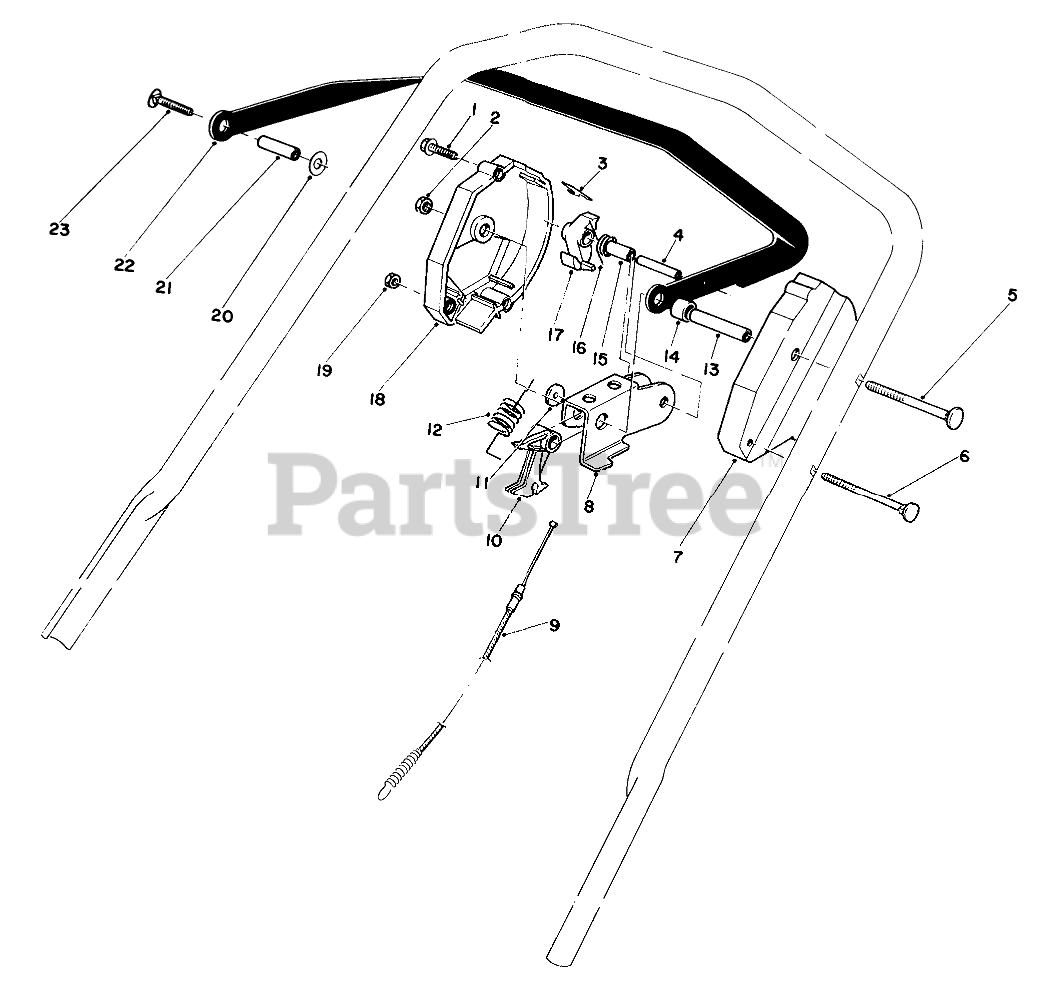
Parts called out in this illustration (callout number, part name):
1	SCREW-HWHTF
2	NUT-LOCK, NI
3	LEAF SPRING
4	PIN-ROLL, SLOTTED
5	5/16-18 X 3 HNDLE SCREW
6	HANDLE SCREW
7	Housing Control R.H.
8	Rocker
9	Cable-Clutch
10	LEVER-CABLE
11	PLASTIC WASHER
12	Spring-Extension
13	TUBING-SPACER
14	SPACER-NYLON
15	SPACER
16	SPRING-TORSION
17	HOOK-CONTROL
18	HOUSING-CONTROL, LH
19	NUT-LOCK, NI
20	WASHER-FLAT
21	Spacer
22	Bar-Control
23	5/16-18 X 2 HNDLE SCREW
